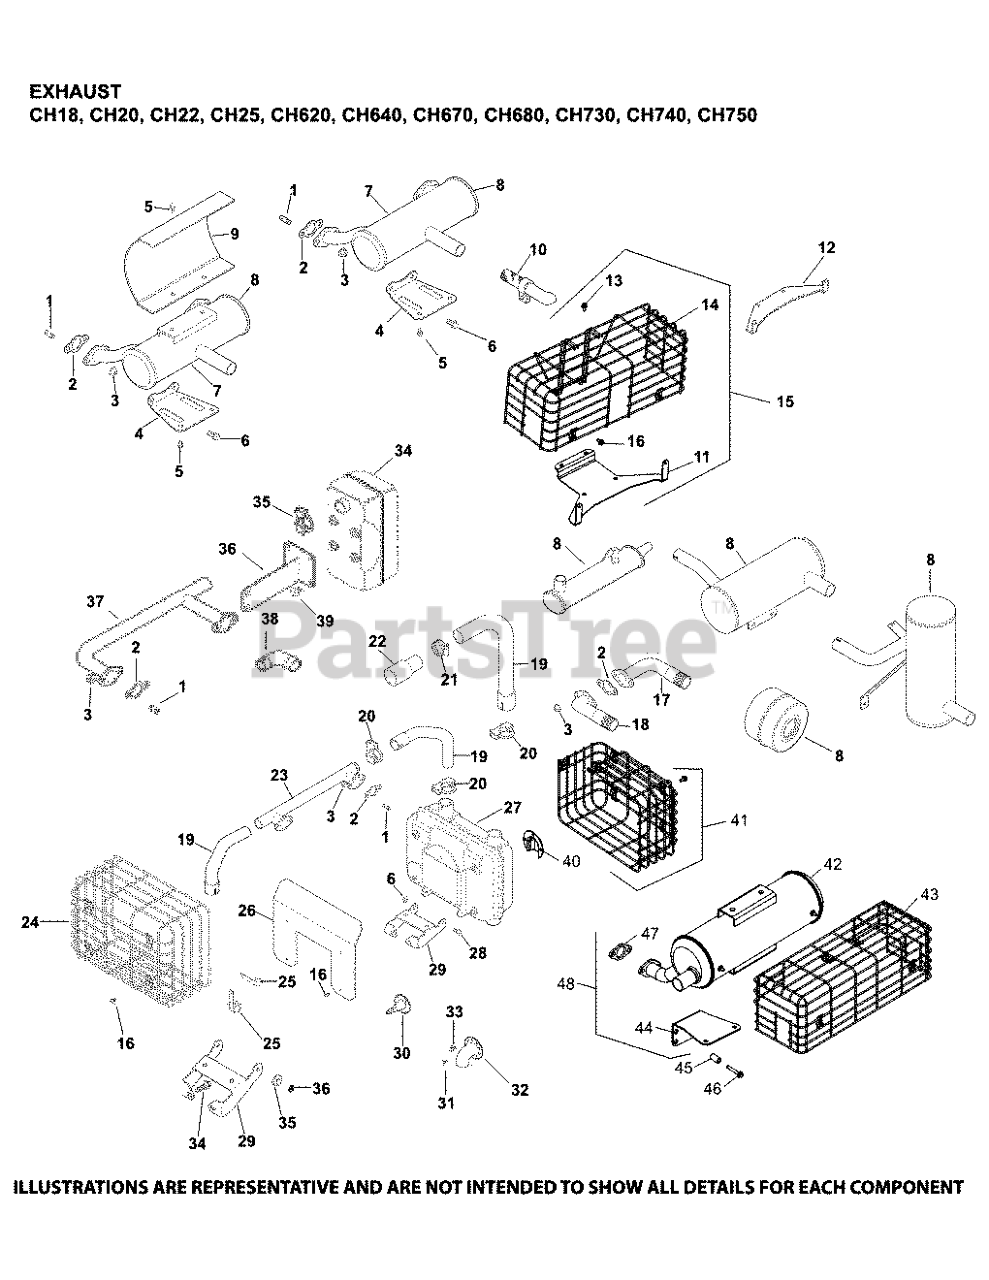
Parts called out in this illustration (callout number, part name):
1	STUD, EXHAUST-USE 25 072 24-S
2	GASKET, EXHAUST
4	NUT, FLG M8X1.25
37	MANIFOLD, EXHAUST
